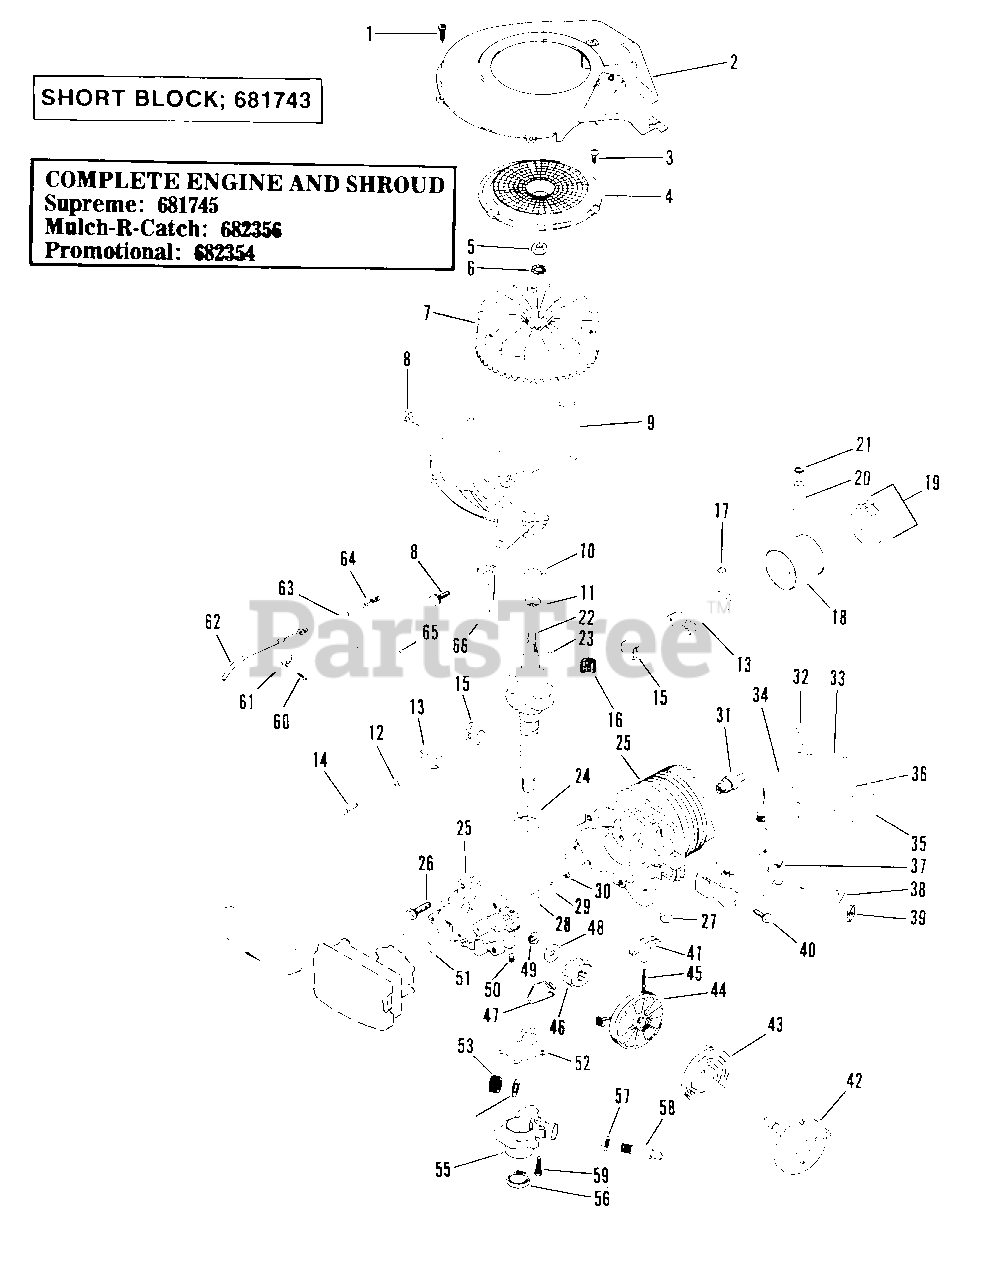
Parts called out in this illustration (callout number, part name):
1	Screw
2	Air Baffle & Eyelet Assembly
3	Screw-Flywheel Screen
4	Screen-Flywheel
5	Nut-Flywheel
6	Lockwasher
7	Flywheel Assembly
8	Screw
9	Base-Shroud
10	Oil Seal-Upper
11	Bearing-Upper
12	Lockplate
13	Connecting Rod Assembly
14	Screw
15	Liner-Split
16	Needle Bearing Set
17	Bearing Assembly
18	Piston & Ring Set
19	Ring Set
20	Wrist Pin
21	Retaining Ring
22	Crankshaft
23	Key-Flywheel
24	Bearing-Lower
25	Cylinder & Crankcase Cover Assembly
26	Screw-Cover to Crankcase
27	Plug
28	Reed
29	Plate-Reed Hold Down
30	Screw-Reed to Crankcase Cover
31	Spark Plug
32	Screw-C.D. Mounting
33	Lead Assembly-Ignition
34	C.D. Ignition Module & Lead Assembly
35	High Tension Lead
36	Spring Terminal
37	Grommet-C.D. Bracket
38	Bracket-C.D. Mounting
39	Clip-"U"
40	Screw
41	Handle-Starter
42	Cup & Pin Assembly
43	Spring
44	Pulley
45	Rope
46	Pinion
47	Spring-Drag
48	Washer
49	Retainer
50	Set Screw-Starter Assembly
51	Gasket-Carburetor to Crankcase Cover
52	Gasket-Gear Box
53	Gear
54	Washer-Thrust
55	Gear Box Assembly
56	Oil Seal-Crankshaft
57	Seal-Driveshaft
58	Driveshaft
59	Screw-Gear Box
60	Screw-Clip-Cable Casing
61	Clip
62	Cable-Interlock
63	Lever-Lockout
64	Spring-Interlock
65	Bolt-Shoulder
66	Bracket-Cable
